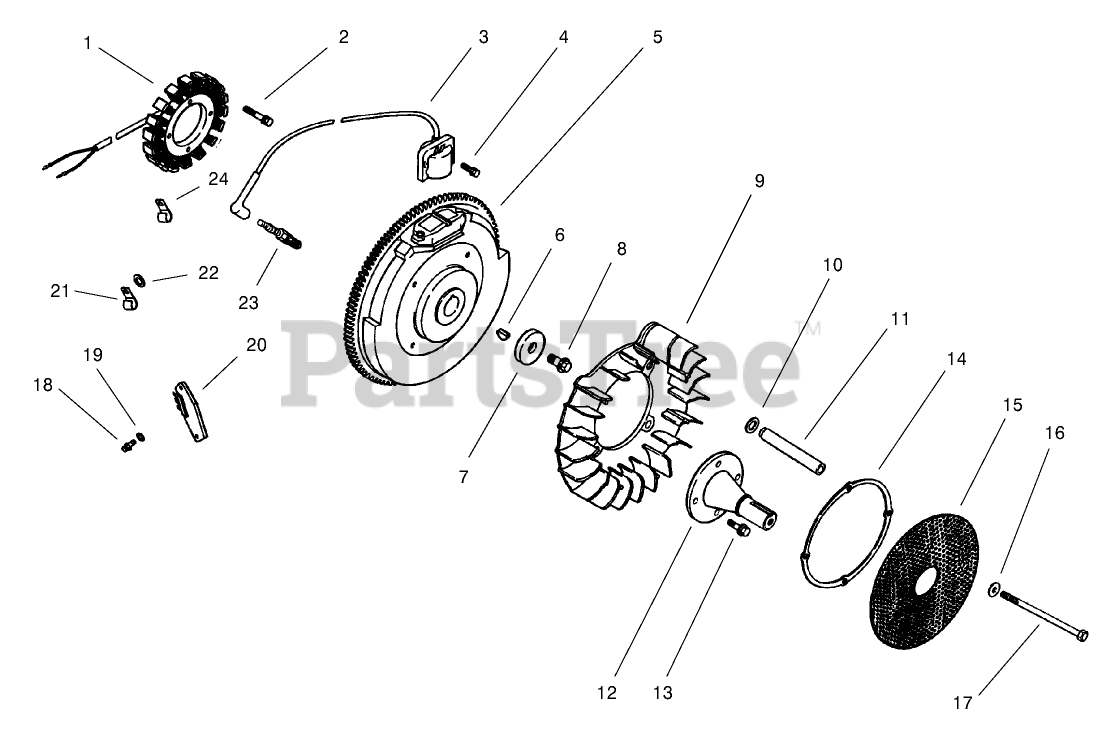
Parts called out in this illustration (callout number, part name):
1	Stator Kit, 15 Amp
2	Screw
3	Module-Ignition
4	Screw
5	Flywheel Assembly
6	Key
7	Washer
8	Screw
9	Fan (Only On: 72103, 72083)
10	Washer, sping
11	Spacer
12	Shaft, front drive
13	Screw M8x1.25x22 (Only On: 72042, 72043, 72062, 72063)
14	Ring-Support
15	Screen-Grass
16	Washer
17	Screw-Hex
18	Screw
19	Washer
20	Rectifier-Regulator
21	Clip
22	Washer
23	Spark Plug
24	Clip
